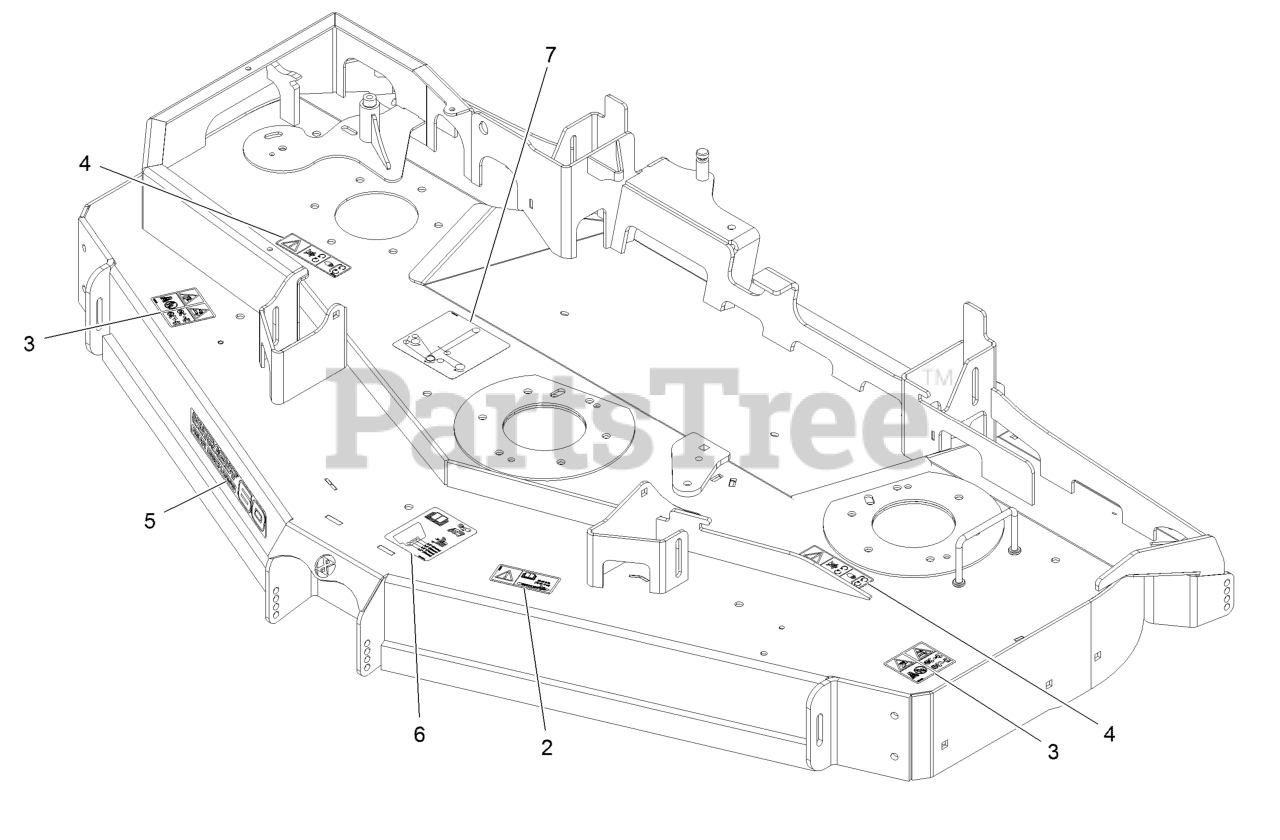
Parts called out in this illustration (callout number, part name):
2	Decal-Bolt Torque
3	Decal-Danger, Thrown Object
4	Decal-Cover, Missing
5	Decal, 60Rd
6	Decal-Roller, Anti-Scalp
7	Decal-Routing, Belt
